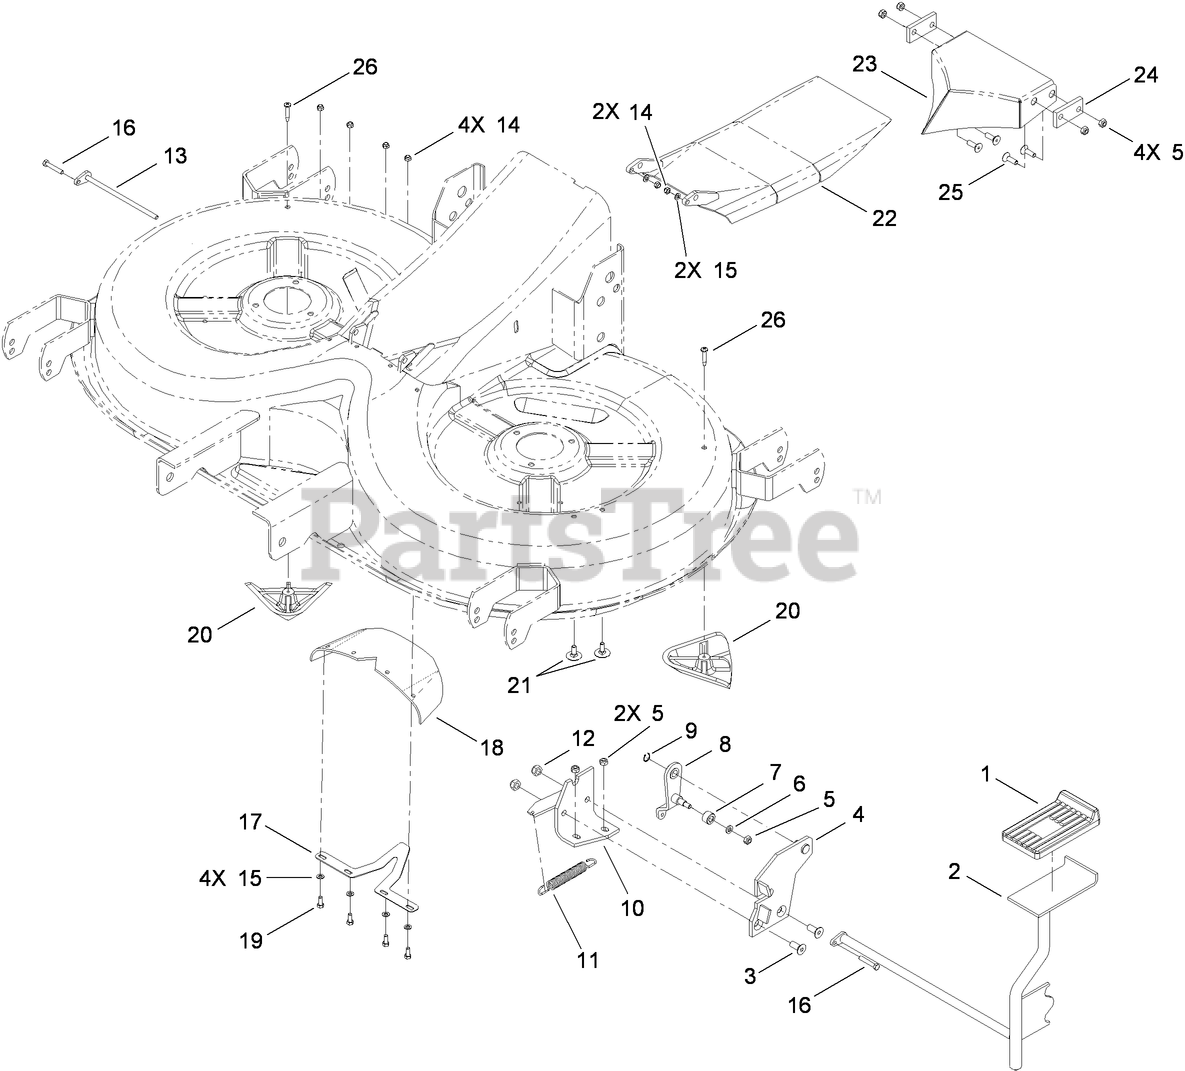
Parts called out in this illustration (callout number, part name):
1	Cover-Lever, FOOT
2	Lever-Foot
3	SCREW-HSFH
4	Plate-Stop
5	NUT-LOCK
6	WASHER-FLAT
7	Roller
8	Lever-Spring
9	RING-LOCKING
10	Bracket-Mounting
11	Spring
12	NUT
13	Rod-Door, Mulch
14	NUT-LOCK
15	WASHER
18	Gasket-Door, Mulch
19	Screw-HH
20	Kicker
21	SCREW-CARR
23	Baffle-Center
24	PLATE-BAFFLE, CENTER
26	SCREW-TAP, PPH
